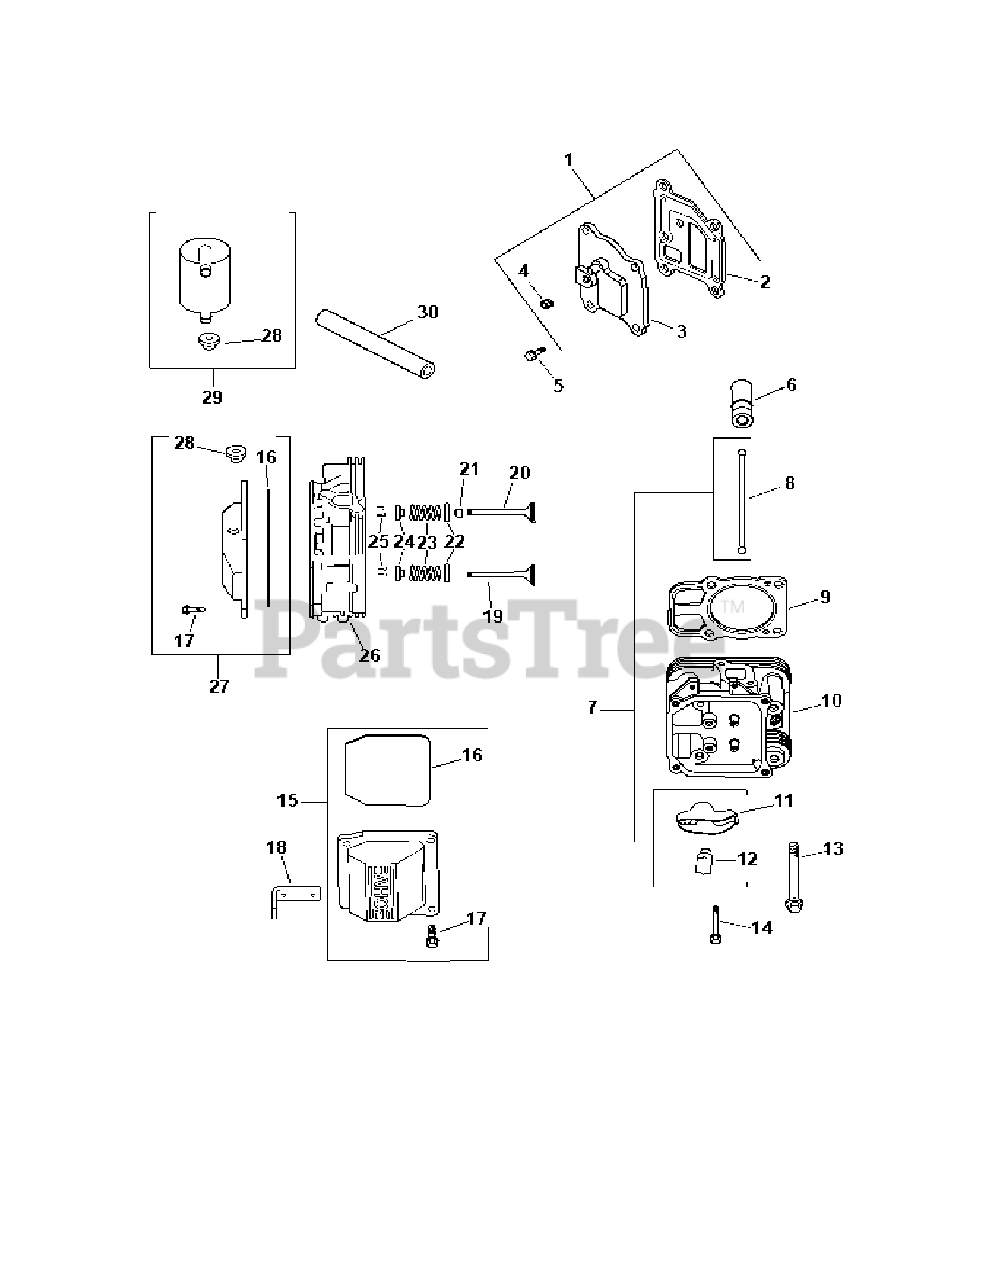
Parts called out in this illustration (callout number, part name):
1	Breather Cover Kit
2	Brather Gasket
3	Breather Cover
4	1/8" Pipe Plug
5	Hex Flange Screw
6	Valve Lifter
7	Valve TrainKit
9	Cylinder Head Gasket
10	Cylinder Head Assembly #2
12	Rocker Arm Pivot
13	Hex Flange Screw
14	Rocker Arm Pivot Screw
15	Rocker Cover Kit
16	O-Ring
17	Hex Flange Screw
18	Lifting Strap
19	Exhaust Valve
20	Intake Valve
21	Valve Stem Seal
23	Valve Spring
24	Valve Spring Retainer
25	Retainer Kit
26	Cylinder Head Assembly #1
27	Rocker Cover (Separator) Kit
28	Rubber Grommet
29	Breather Separator Kit
30	Breather Hose
